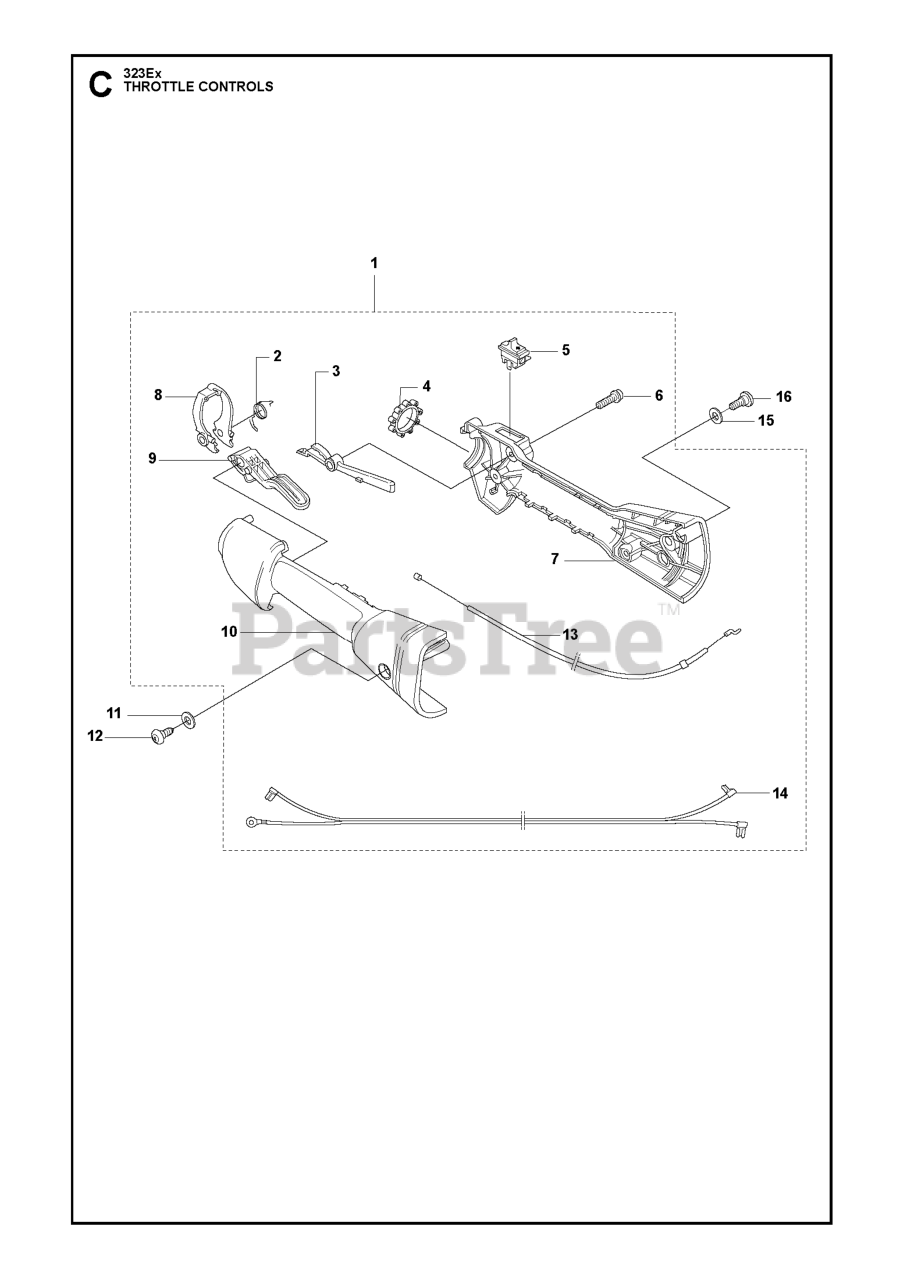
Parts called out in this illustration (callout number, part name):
3	THROTTLE LOCK
4	VIBRATION DAMPER
5	START/STOP SWITCH
6	SCREW
7	HSG THROTTLE RH
9	THROTTLE TRIGGER
10	HANDLE HALF HSG LH
11	O-RING 8X1.6
12	SCREW MT5X11
13	WIRE
15	O-RING 8X1.6
16	SCREW MT5X11
